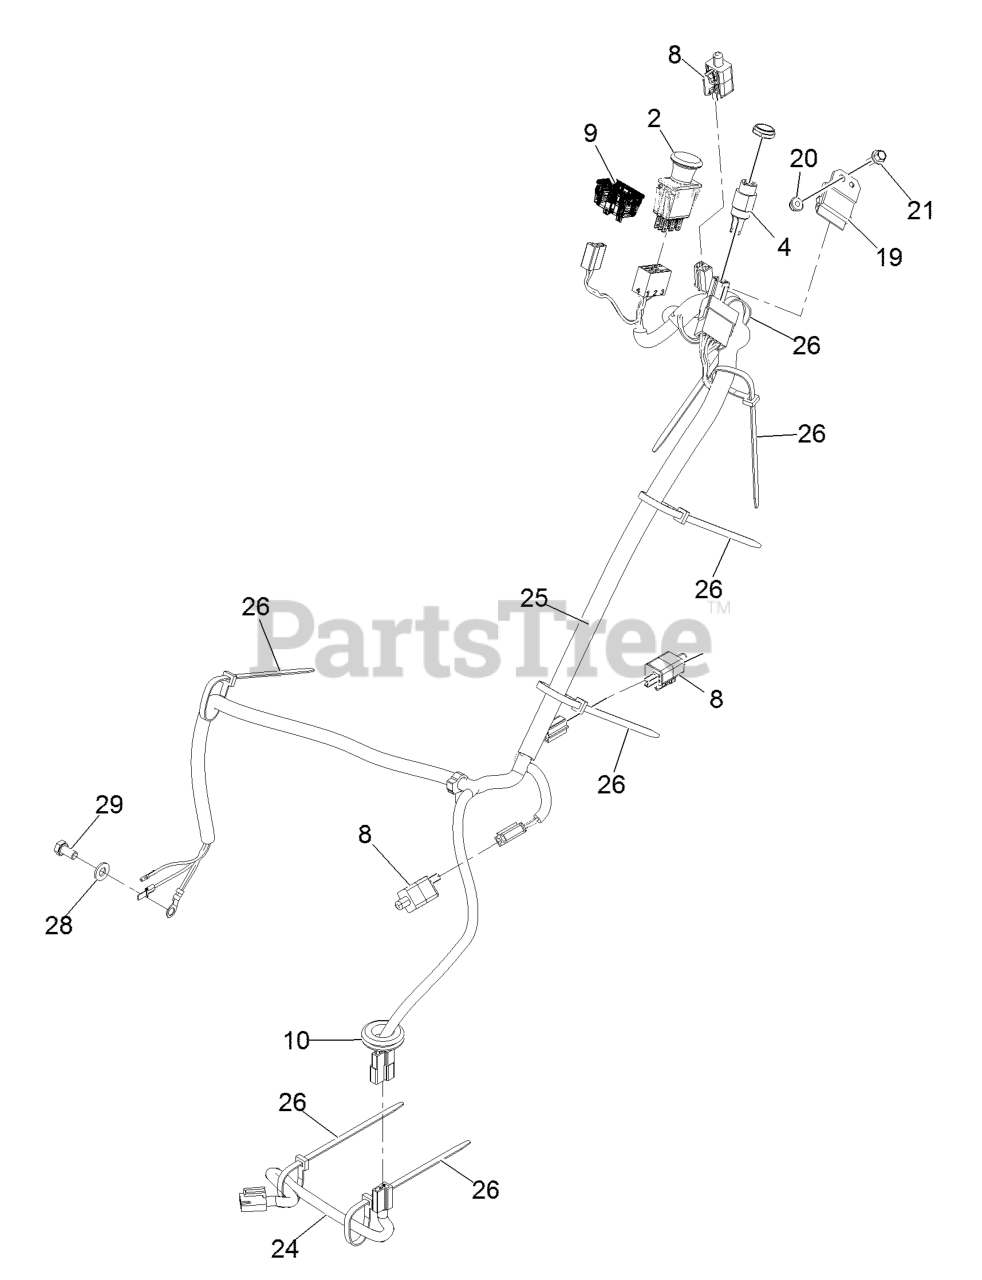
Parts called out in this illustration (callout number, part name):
2	SWITCH-PTO
4	SWITCH & KEY (INCLUDES NU
4	NUT-SWITCH, IGNITION
9	METER-HOUR
10	GROMMET
19	MODULE-INTERLOCK
21	SCREW-HEAD, FLANGE
24	HARNESS-CLUTCH PIGTAIL
25	HARNESS-MAIN
26	TIE-PLASTIC
28	WASHER-PLAIN
29	SCREW-HH
